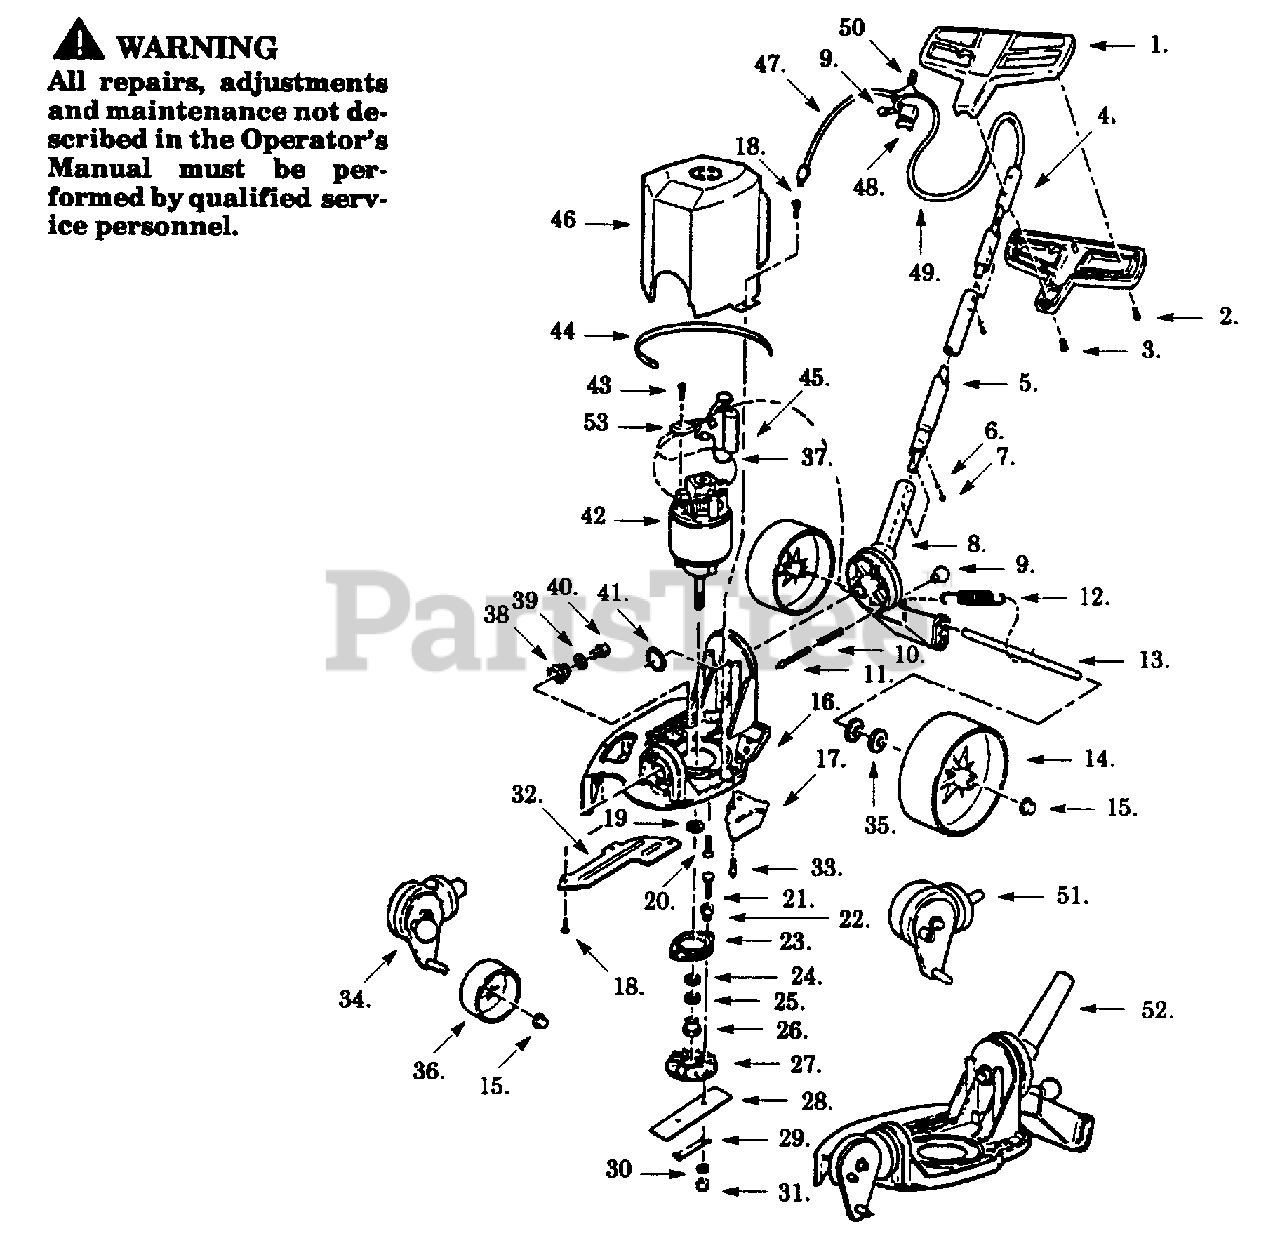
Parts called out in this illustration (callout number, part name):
1	Top & Bottom Handle
4	Upper Handle Tube
5	Lower Handle Tube
6	Lockwasher
8	Swivel Casting
9	Capacitor
10	Swivel Lock Spring
11	Swivel Lock Shaft
14	Rear Wheel
15	Push Nut
17	Guide Blade
22	Insulating Sleeve
23	Clutch Plate
26	Clutch Sleeve
28	Blade Cutter
29	Lock Strap
30	Lockwasher
32	Guard Plate
33	Pop Rivet
34	Front Swivel Ass'y.
37	Fiberglass Sleeve
38	Front Swivel Spring
41	Retaining Ring
44	Tie Strap
45	Resistor
46	Motor Cover
47	Power Cord
49	Harness Ass'y.
50	Connector
51	Front Swivel Ass'y.
52	Edger Frame Ass'y.
53	Rectifier
